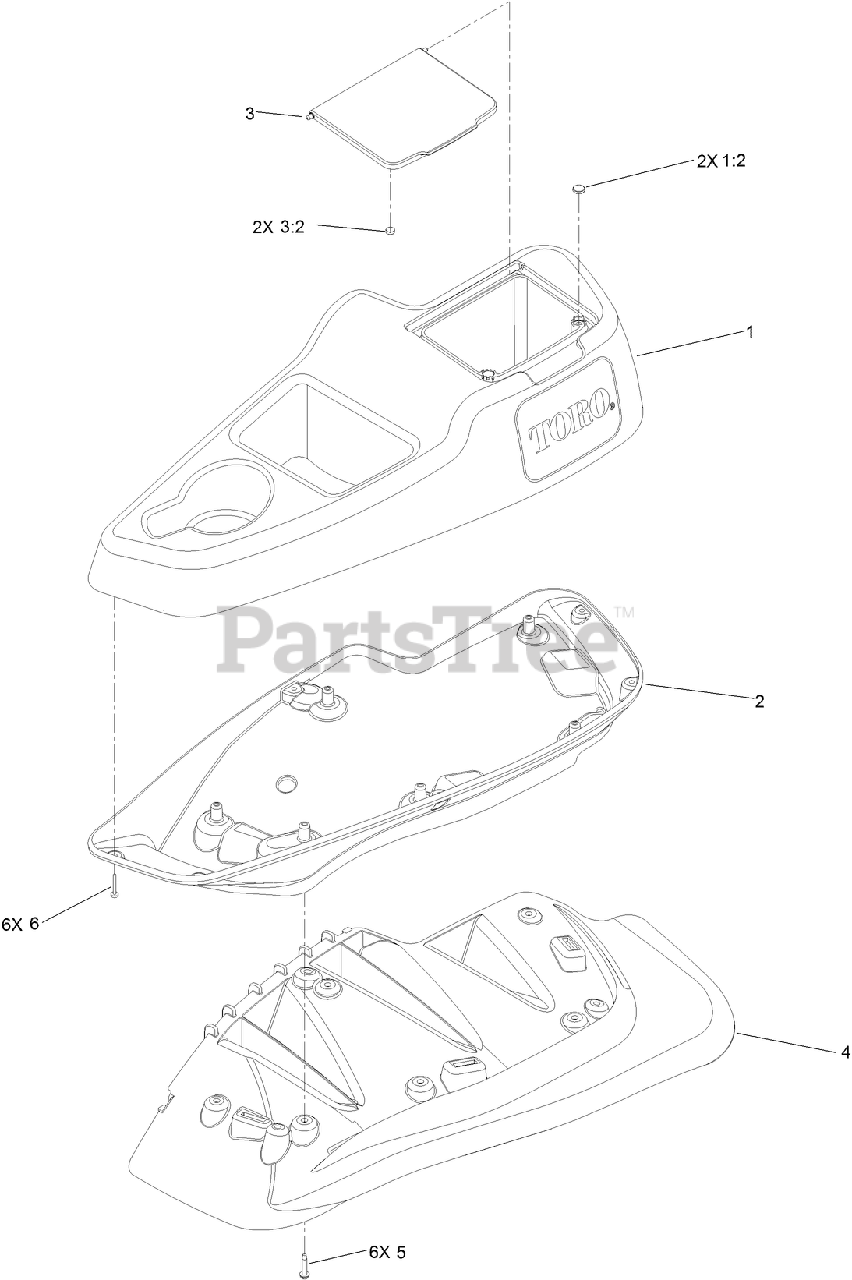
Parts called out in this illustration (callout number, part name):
1	LH WIDE CONSOLE TOP ASM
2	CONSOLE-LOWER, LH WIDE
3	WIDE LID ASM
3:2	MAGNET
4	FENDER-WIDE, LH
5	SCREW-THREAD FORMING
6	SCREW-PPH
